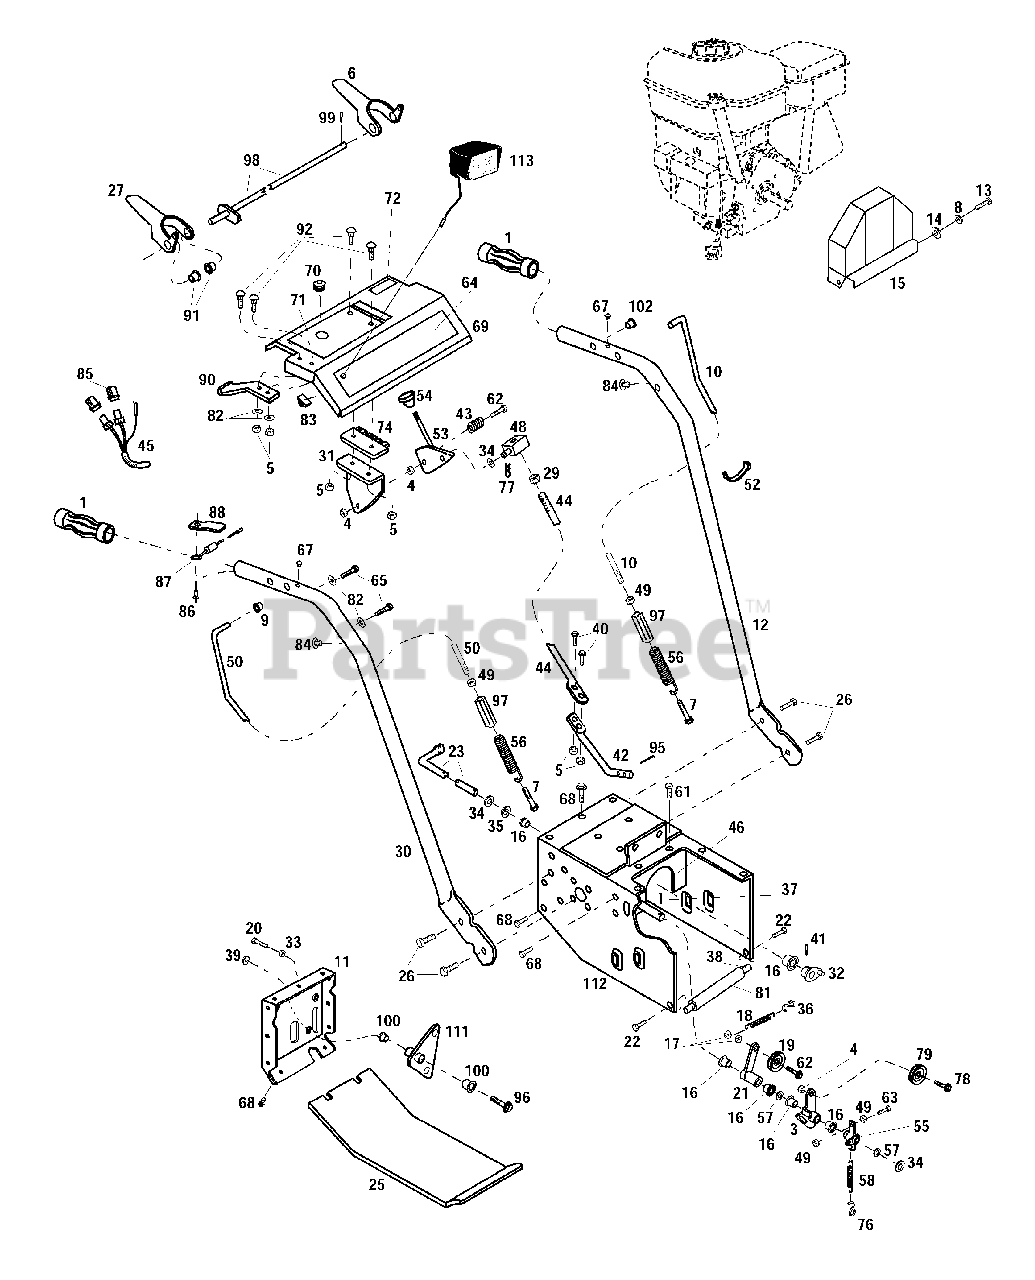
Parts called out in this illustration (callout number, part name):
1	Handle Grip
3	Idler Arm
4	Lock Nut, 3/8-16
5	Lock Nut, 1/4-20
6	Left Control Handle
7	Fillister-Head Bolt, 5/16-18 x 1
8	Lock Washer, 5/16
9	Push Nut
10	Wheel Drive Clutch Rod
11	Back Plate
12	Left Handlebar
13	Hex Hd. Screw, 5/16-18 x 3/4
14	Flat Washer, 5/16
15	Belt Cover
17	Self-Locking Jam Nut, 3/8-16
18	Extension Spring
19	Idler Pulley
20	Flange Screw, 5/16-18 x 1-3/4
21	Idler Arm
22	Flange Screw, 5/16-18 x 3/4
23	Control Arm
25	Bottom Cover
26	Flange Screw, 3/8-16 x 3/4
27	Right Control Handle
29	Hex Nut, 3/8-16
30	Right Handlebar
31	Control Bracket
32	Control Arm
33	Jam Nut, 5/16-18
34	Flat Washer, 1/2
35	Bowed Washer
36	S-Hook
37	Cotter Pin, 3/32 x 1
38	Cross Member
39	Flange Nut, 3/8-16
40	Hex Hd. Cap Screw, 1/4-20 x 3/4
41	Drive Pin, 1/8 x 3/4
42	Lower Control Rod
43	Compression Spring
44	Upper Control Rod
45	Wiring Harness
46	Support Assembly
48	Pivot Block
49	Hex Nut, 1/4-20
50	Auger Control Rod
52	Plastic tie
53	Shift Control Arm
55	Brake Arm
56	Extension Spring
57	Flat Washer, 1/2"
58	Extension Spring
61	Flange Screw, 5/16-18 x 1/2
62	Hex Hd. Cap Screw, 3/8-16 x 1-3/4
63	Hex Hd. Cap Screw, 1/4-20 x 1
64	Logo Decal
65	Thread-Forming Screw, 1/4-20 x 5/8
67	Wear Button
68	Thread-Forming Screw, 5/16-18 x 3/4
69	Console
70	Flip Grommet
71	Instructions Decal
74	Shift Quadrant
77	Cotter Spring
78	Hex Hd. Screw, 3/8-16 x 2
79	Idler Pulley
81	Plastic Tubing
82	Flat Washer, 1/4
83	Cord Clip
85	Connector Body
86	Pop Rivet, 1/8
87	Resistor
88	Clamp
90	Flat Spring
91	Flange Bearing
92	Round Head Screw, 1/4-20 x 5/8
95	Cotter Pin, 3/32 x 3/4
96	Shoulder Bolt
97	Adjusting Nut
98	Control Rod
99	Roll Pin, 1/8 x 5/8
100	Nyliner Flange Bushing
102	Flange Bearing
103	Troy-Bilt Red Spray Paint, 13 oz
104	Troy-Bilt Black Spray Paint, 13 oz
111	Speed Control Arm
112	Frame
113	Light Kit
